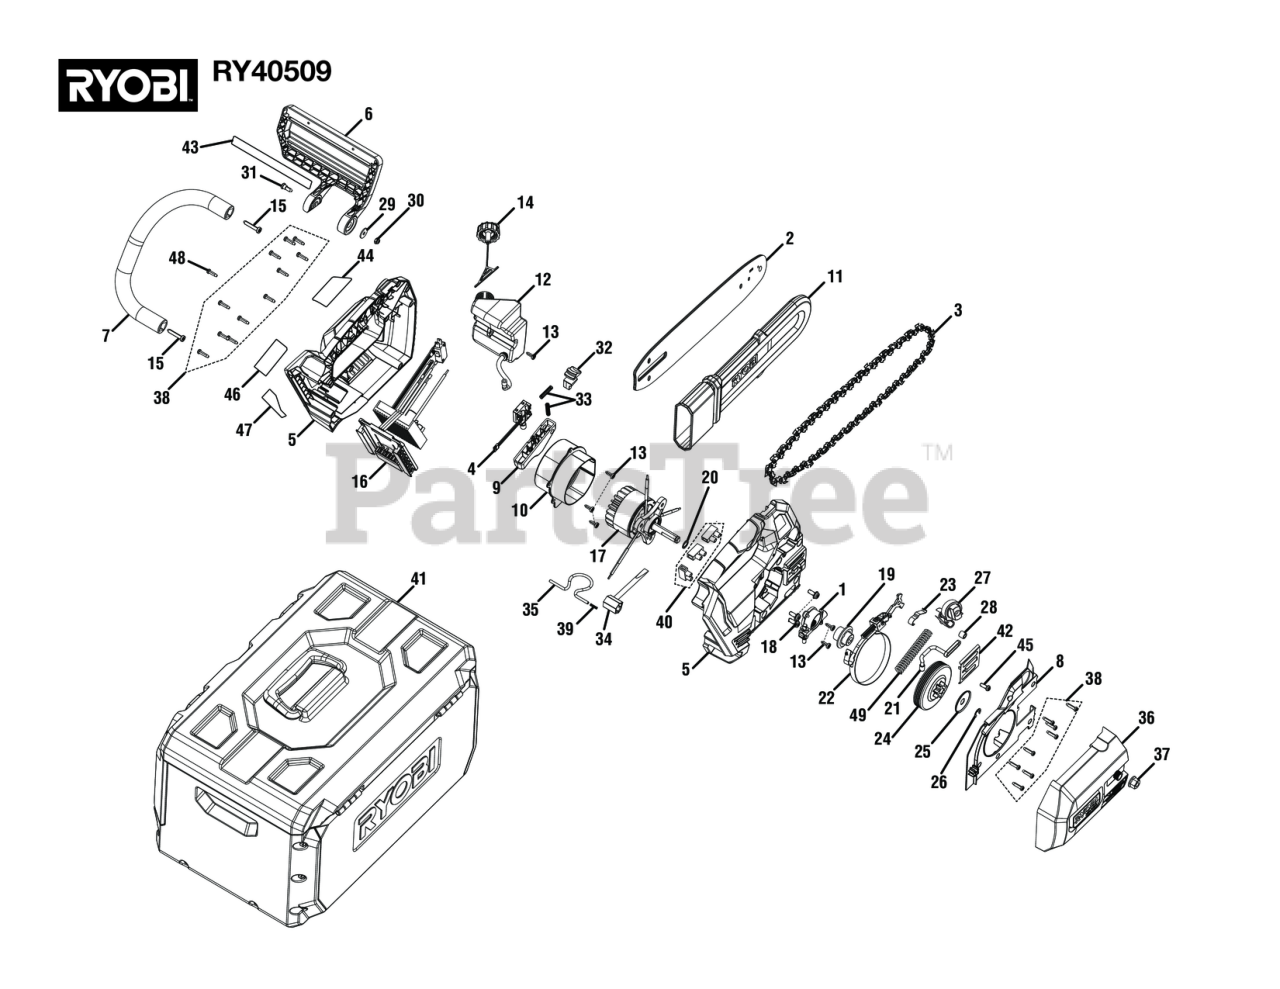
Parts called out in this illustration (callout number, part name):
1	Oil Pump Assembly
2	12 in. Bar
3	Chain (12 in.)
4	Variable Switch
5	Housing Assembly (Inc. Key Nos. 44 & 46-47)
6	Front Guard Assembly (Inc. Key No. 43)
7	Front Handle
8	Brake Mechanism Cover
10	Motor Volute
12	Oil Tank Assembly
13	Screw (M4.2 x 12 mm, T20 Torx Pan Hd.)
14	Oil Tank Cap Assembly
15	Screw (M5 x 25 mm, T25 Torx Pan Hd.)
16	Motor Controller, Switch, and Battery Connector Assembly
18	Screw, T25, M5X8, Steel, Black ZincePlat
19	Oil Pump Drive
21	Oil Output Tube
22	Brake Band Assembly
24	Sprocket w/ Drum
25	Washer (Special)
27	Chain Brake Assembly
28	Hand Guard Insert
29	Washer (ID5.2 x OD16 x 1.5t)
31	Screw (M5 x 15 mm, T25 Torx Hd.)
32	Trigger Lock-Out
33	Compression Spring (Trigger Lock)
35	Hook Spring
36	Sprocket Cover and Chain Tension Assembly
37	Hex Nut (5/16-18 Flange)
38	Screw (M4 x 16 mm, T20 Torx Socket Pan Hd.)
39	Metal Loop Spring
40	Terminal Block w/Screw
41	Carry Case
42	Guide Bar Plate
43	Icons Label
44	Warning Danger Label
45	Screw, M4-18 x 12mm, T20 Torx Pan Head
46	Data Label
48	Screw (M4 x 14 mm, T15 Torx Pan Hd.))
